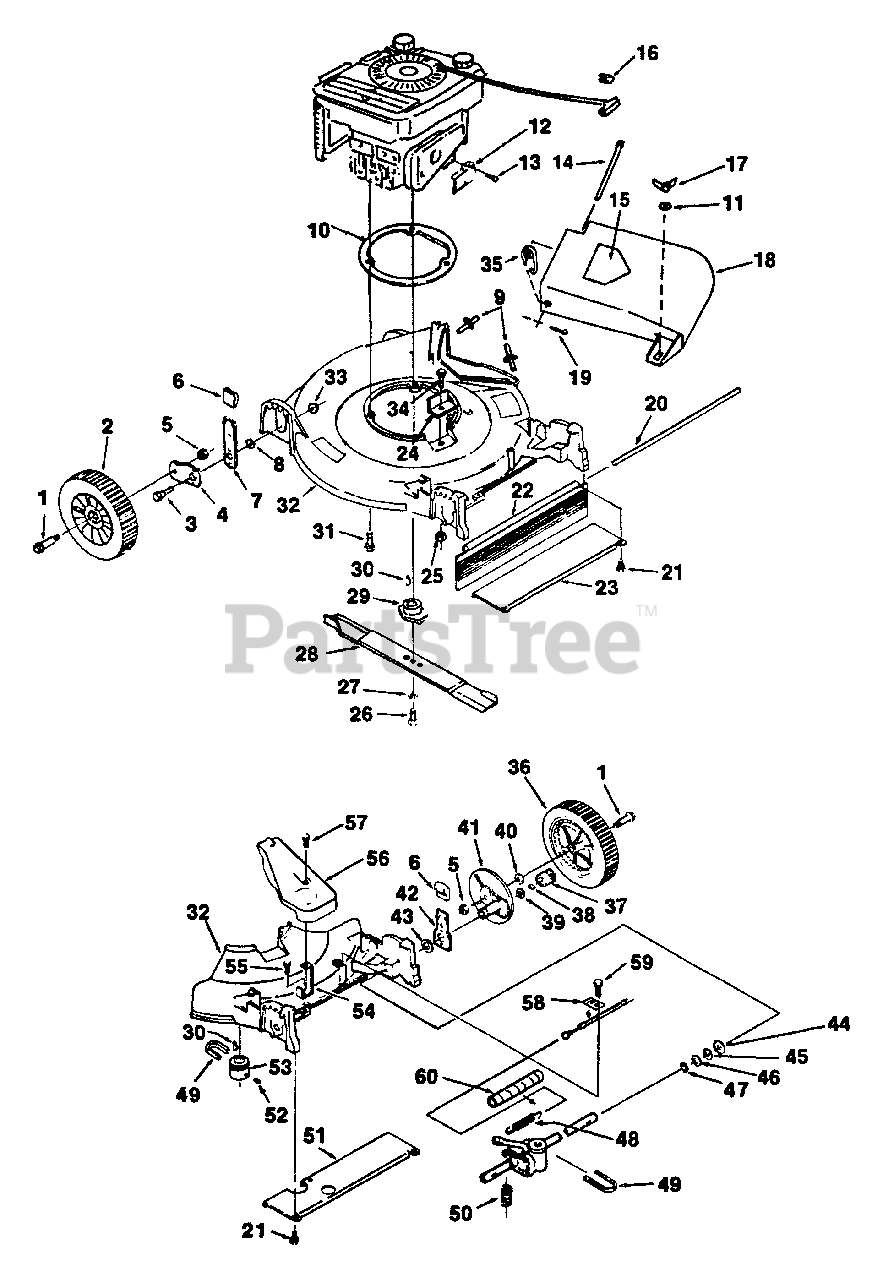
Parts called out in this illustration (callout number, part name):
1	AXLE ASSY
2	WHEEL ASSY
3	BOLT - 5/16 X 18
4	ARM - WHEEL ADJUSTING
5	NUT - 3/8-24
6	KNOB
7	INDEXING ASSY
8	SPACER
9	STUD
10	RING - Engine
11	WASHER - 1/4"
12	DEFLECTOR
13	SCREW - 8-32 X 3/8"
14	PIN - HINGE
15	LABEL - WARNING
16	GUIDE, ROPE
17	WINGNUT
18	DISCHARGE COVER
19	PIN, SPLIT
20	ROD
21	SCREW - 1/4-20 X 3/4"
22	FLAP - Drag
23	COVER - REAR
24	COVER, BELT
25	LOCKNUT - 1/4-20
26	SCREW - .375 X 1.2" -- HEX CAP
27	LOCKWASHER - 3/8"
28	BLADE, MOWER
29	ADAPTOR
30	KEY
31	SCREW - 3/8-16 X 1 1/2"
32	DECK
33	NUT - 5/16-18 -- FLANGE
34	SCREW - 1/4-20 x 1/2"
35	SPRING
36	WHEEL ASSY
37	PINION - RIGHT HAND
38	PAWL
39	WASHER
41	DRIVE WHEEL SUPPORT ASSY
42	INDEXING ASSY
43	SPACER
44	WASHER
45	WASHER
46	WASHER
47	RING, RETAINING
48	SPRING
49	BELT, DRIVE
50	SPRING
51	COVER - REAR
52	SCREW - 1/4-20 X 3/8"
53	PULLEY - Drive
54	BRACKET
55	SCREW - 1/4-20 X 9/16"
56	COVER - DRIVE
57	SCREW - 1/4-20 X 3/4"
58	CLAMP
59	SCREW - 1/4-20 X 5/8"
60	COVER - Spring
